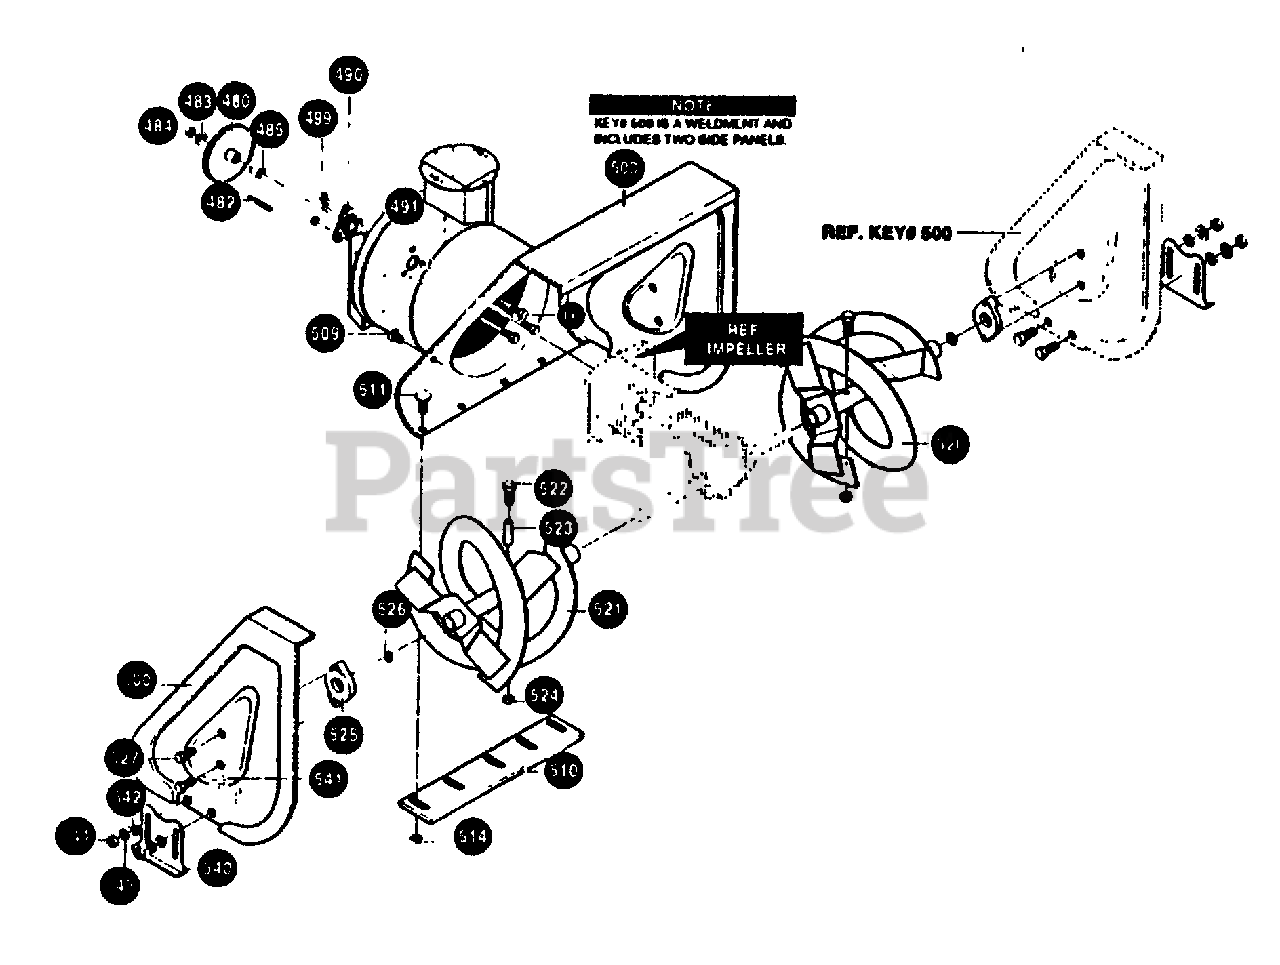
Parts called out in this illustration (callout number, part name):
480	PULLEY, V4L 8.40 OD
482	KEY, SQUARE
483	WASHER, FLAT .53 X1.00X.063
484	NUT, 1/2-20
485	SPACER, SLEEVE
490	RETAINER, BALL
491	BEARING, BALL
493	SCREW, 5/16-18X .75
499	NUT, 5/16-18
500	HSNG, ASSY
510	BLADE, SCRAPER
511	BOLT, 5/16-18X 75
514	NUT, 5/16-18
520	AUGER, ASSY LH
521	AUGER, ASSY RH
522	SCREW, 1/4-20X1.75
523	SPACER. SLEEVE
524	NUT. 1/4-20 RGHXCTRLK
525	AUGER SHAFT BEARING
526	FLATWASHER 1.005X1.31X.035
527	SCREW, 5/16-18X .75
540	SKID. HEIGHT ADJUST
541	BOLT, 5/16-18X .75
542	FLATWASHER .344X.69X.065
543	WASHER 328X.60X.09
544	NUT, 5/16-18 REGHEX
